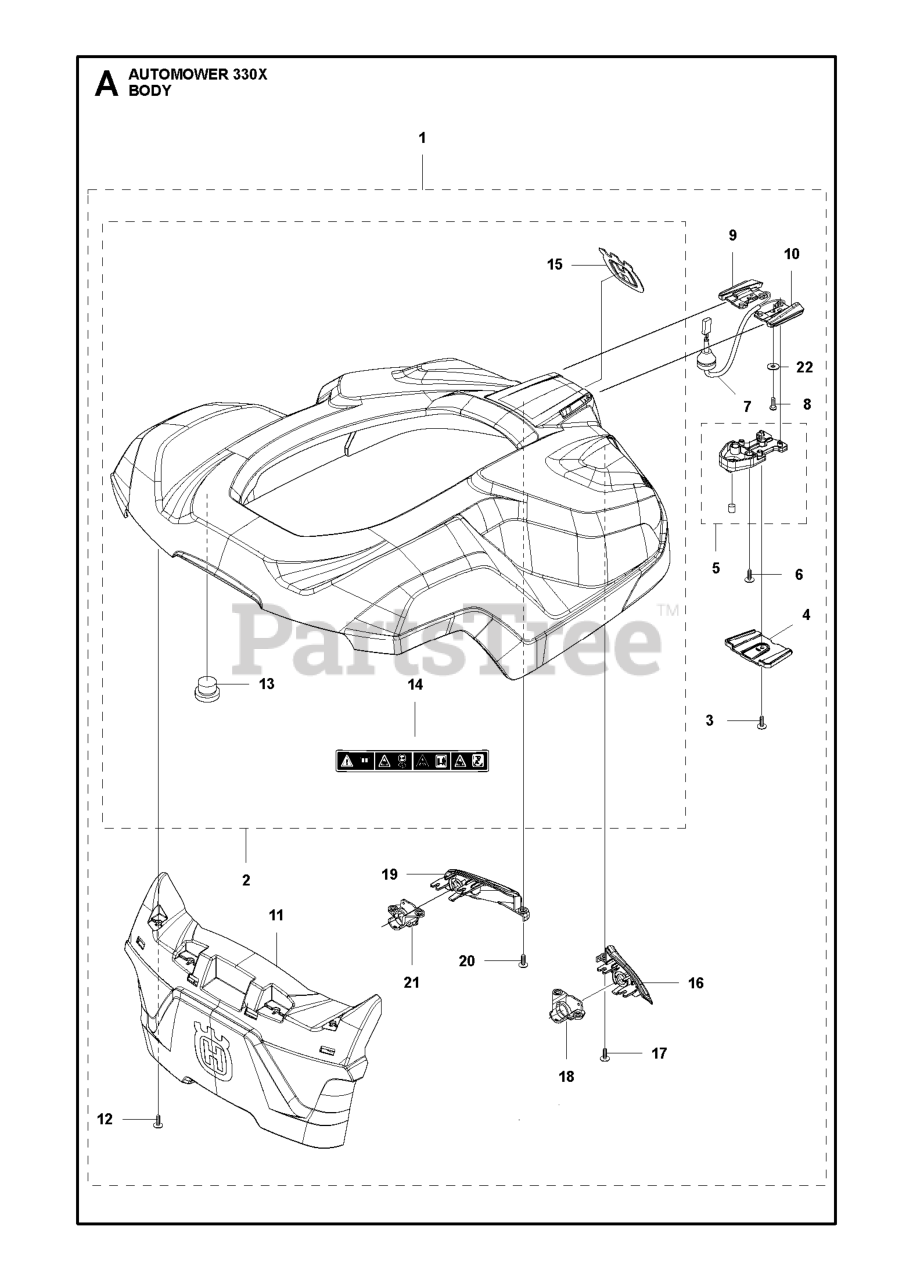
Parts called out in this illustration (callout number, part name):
2	BODY KIT GREY
3	SCREW 14MM
6	SCREW 14MM
11	BUMPER REAR
12	SCREW ITXPANT
13	CAP SNAPLOC
14	LABEL WARNING P15
15	DECAL HUSQVARNA CROWN HEIGHT 5
16	INSERT US-SENSOR RIGHT - GREY
17	SCREW 14MM
18	HOLDER US-SENSOR RIGHT, BLANK
19	INSERT US-SENSOR LEFT - GREY
20	SCREW 14MM
